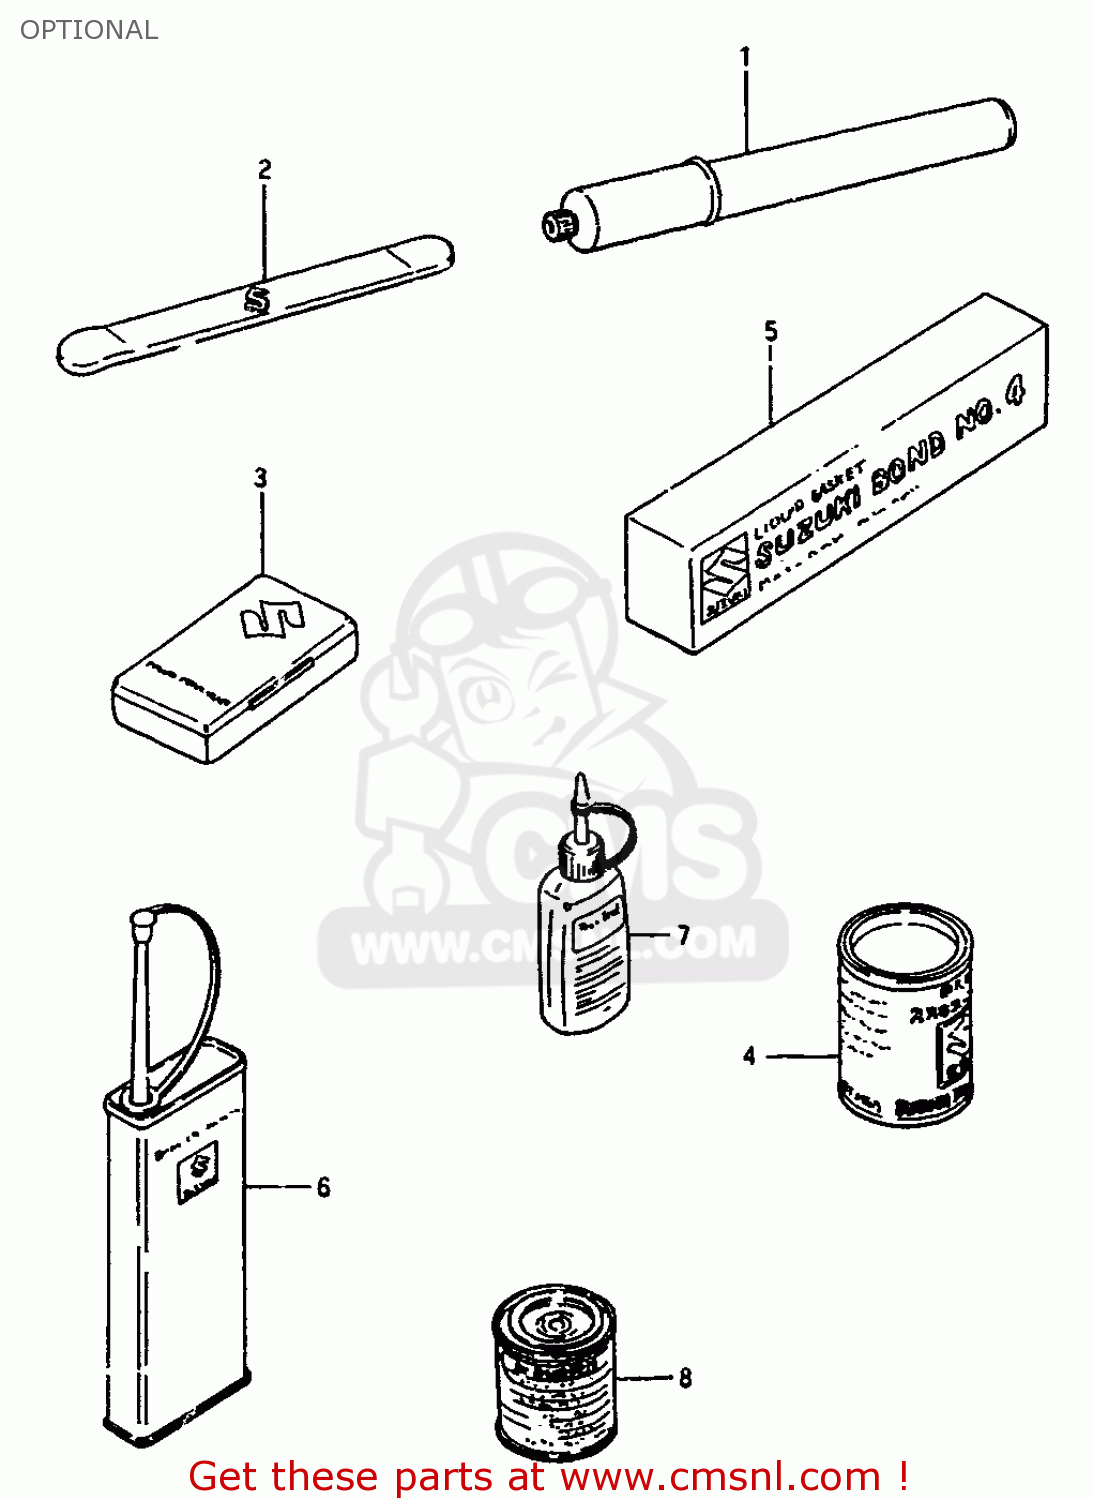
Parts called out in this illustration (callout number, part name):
1	INFLATOR, AIR
2	LEVER,TIRE
3	TUBE REPARING TOOL
4	GREASE(C)EP2 LITHIUM 150G
5	BOND 1104
6	THREAD LOCK NO.1401 CLEAR 200G
7	** SUPERSEEDED
8	PAINT,BLACK
